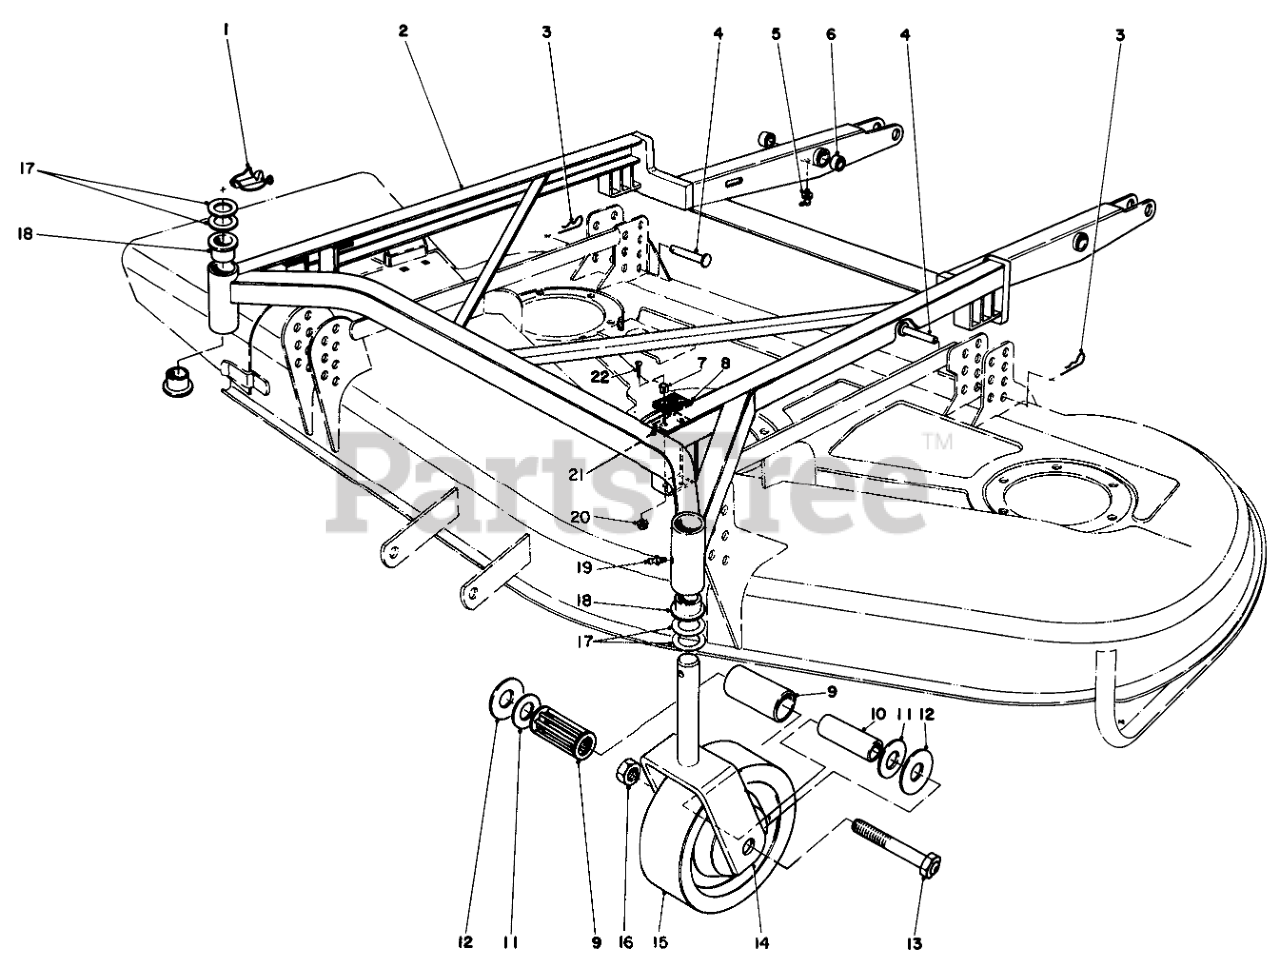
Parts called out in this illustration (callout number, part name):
1	PIN-LYNCH
2	Frame-Deck Suspension (Incl. Ref. #5-6 & 19)
3	PIN-HAIR
4	PIN-CLEVIS
5	FITTING-GREASE, 90 DEG
6	7/8 ID X 1.128 X 7/8 LG BSHG
7	SPACER
8	CUSHION-RUBBER
9	ROLLER BEARING
10	BUSHING
11	BEARING RETAINER
12	THRUST WASHER
13	AXLE ASM
14	FORK-Castor
15	Wheel Assy. (Incl. Ref. #9-12)
16	NUT-HEX
17	WASHER-THRUST
18	Bushing
19	FITTING-GREASE
20	NUT-LOCK, NI
21	SHIM-CUSHION
